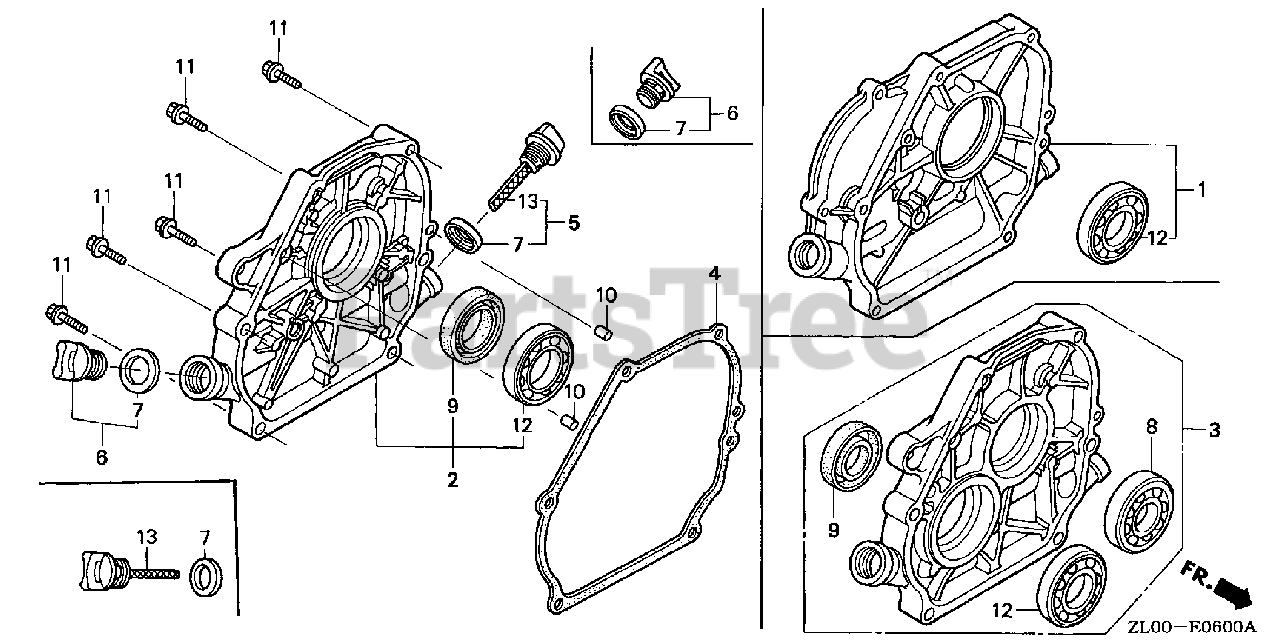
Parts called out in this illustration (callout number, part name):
2	COVER ASSY., CRANKCASE (U-TYPE)
4	GASKET, CASE COVER
5	CAP ASSY., OIL FILLER
6	CAP ASSY., OIL FILLER
7	GASKET, OIL FILLER CAP
9	OIL SEAL (25X41X6)
10	PIN A, DOWEL (8X14)
11	BOLT, FLANGE (8X32)
12	BEARING, RADIAL BALL (6205)
